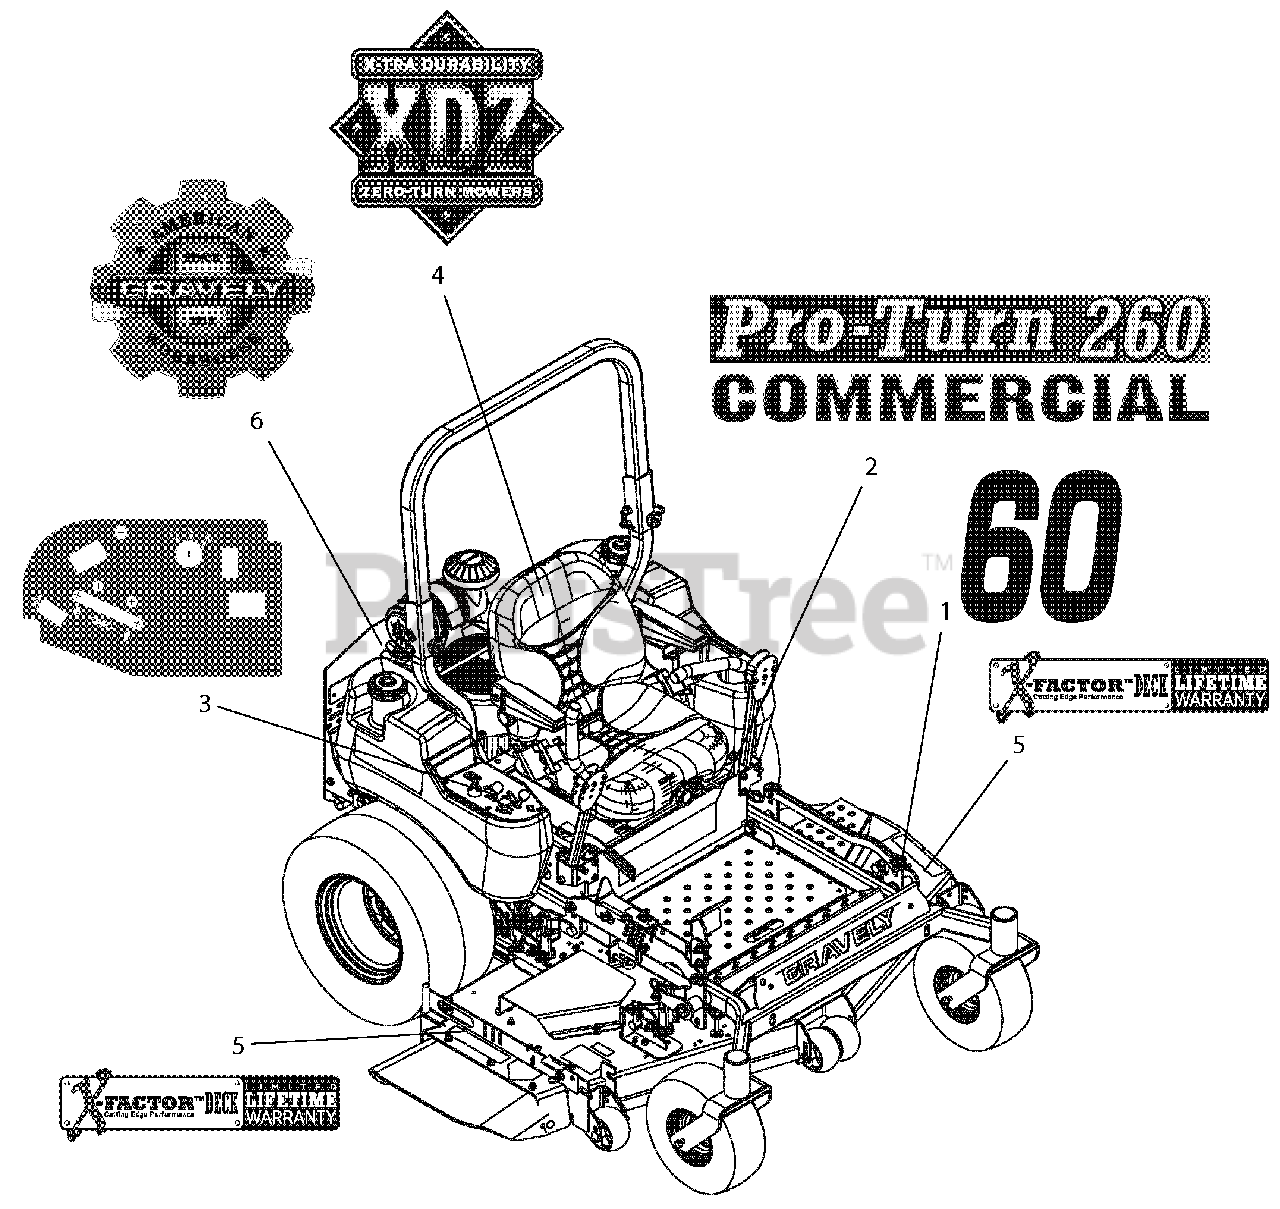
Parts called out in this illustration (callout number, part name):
1	DECAL, 60"
2	DECAL, PROTURN 260
3	DECAL, CONTROL PANEL
4	DECAL, XDZ
5	DECAL, X-FACTOR DECK
6	DECAL, GRAVELY HERITAGE-LARGE
